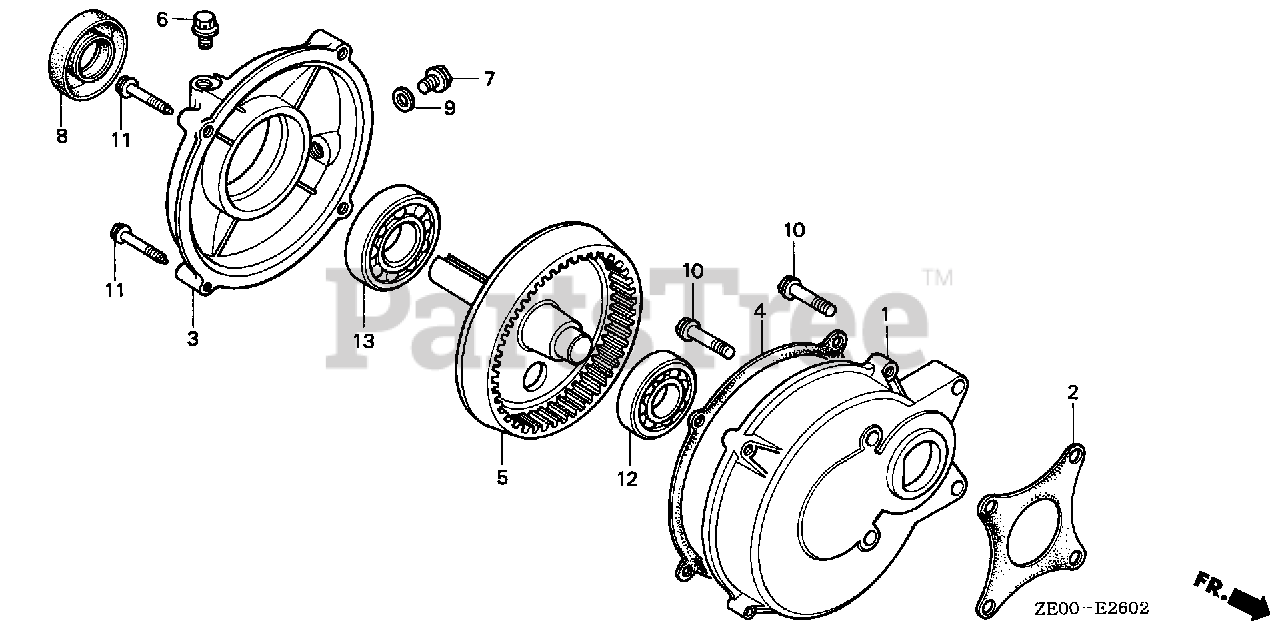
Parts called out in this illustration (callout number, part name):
1	CASE, REDUCTION
2	GASKET, REDUCTION CASE
3	COVER, REDUCTION
4	GASKET, REDUCTION COVER
5	SHAFT, P.T.O. (86T)
6	BOLT, BREATHING
7	BOLT, DRAIN PLUG (12X15)
8	OIL SEAL (25X41X6) (NOK)
8	OIL SEAL (25X41X6)
9	WASHER, DRAIN PLUG (12MM)
10	BOLT, FLANGE (8X32)
11	BOLT, FLANGE (8X35)
12	BEARING, RADIAL BALL (6204)
13	BEARING, RADIAL BALL (6305)
